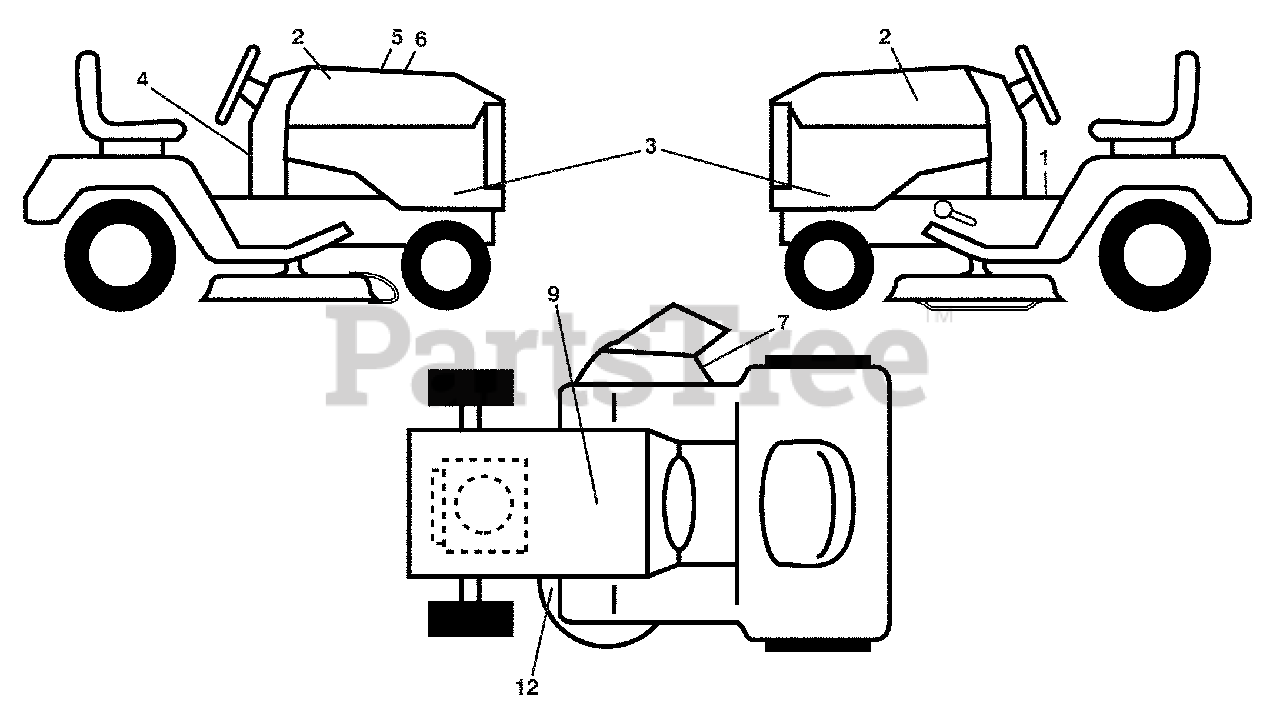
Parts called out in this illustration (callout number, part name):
1	Decal, Fender Warning
2	Decal, Hood
3	Decal, Hood Panel SD
4	Decal, Spark Arrestor
5	Decal, Customer Respons.
6	Decal, Replacement
7	Decal, Mower Warming
9	Decal, Battery Dnge/Poi
12	Decal, Mower V-Belt Schematic
